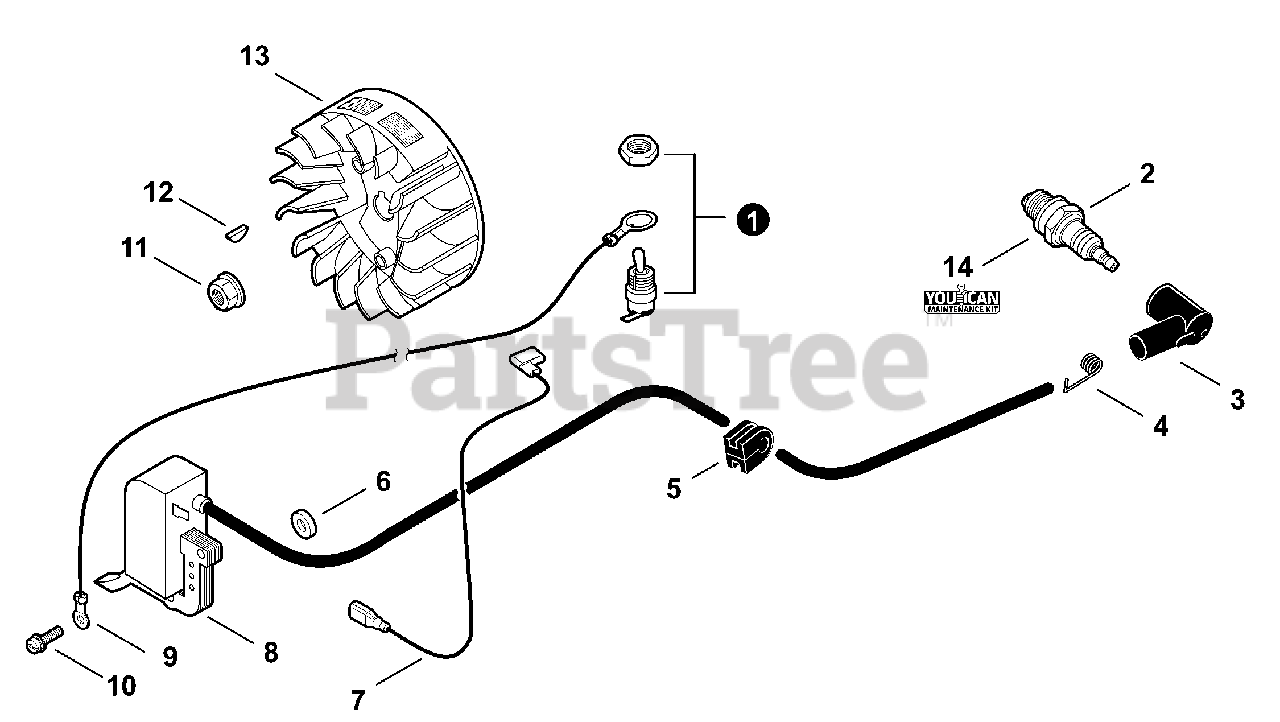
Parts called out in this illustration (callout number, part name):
1	SWITCH, ON-OFF
2	SPARK PLUG - BPMR8Y
3	CAP, SPARK PLUG
4	TERMINAL, SPARK PLUG
6	WASHER 5.2×12×3
7	LEAD - IGNITION L= 95
8	COIL, IGNITION
9	LEAD - GROUND L= 100
10	SCREW 5×22
11	NUT, FLANGE M8
12	KEY, WOODRUFF
13	FLYWHEEL
14	TUNE-UP KIT - YOUCAN™
